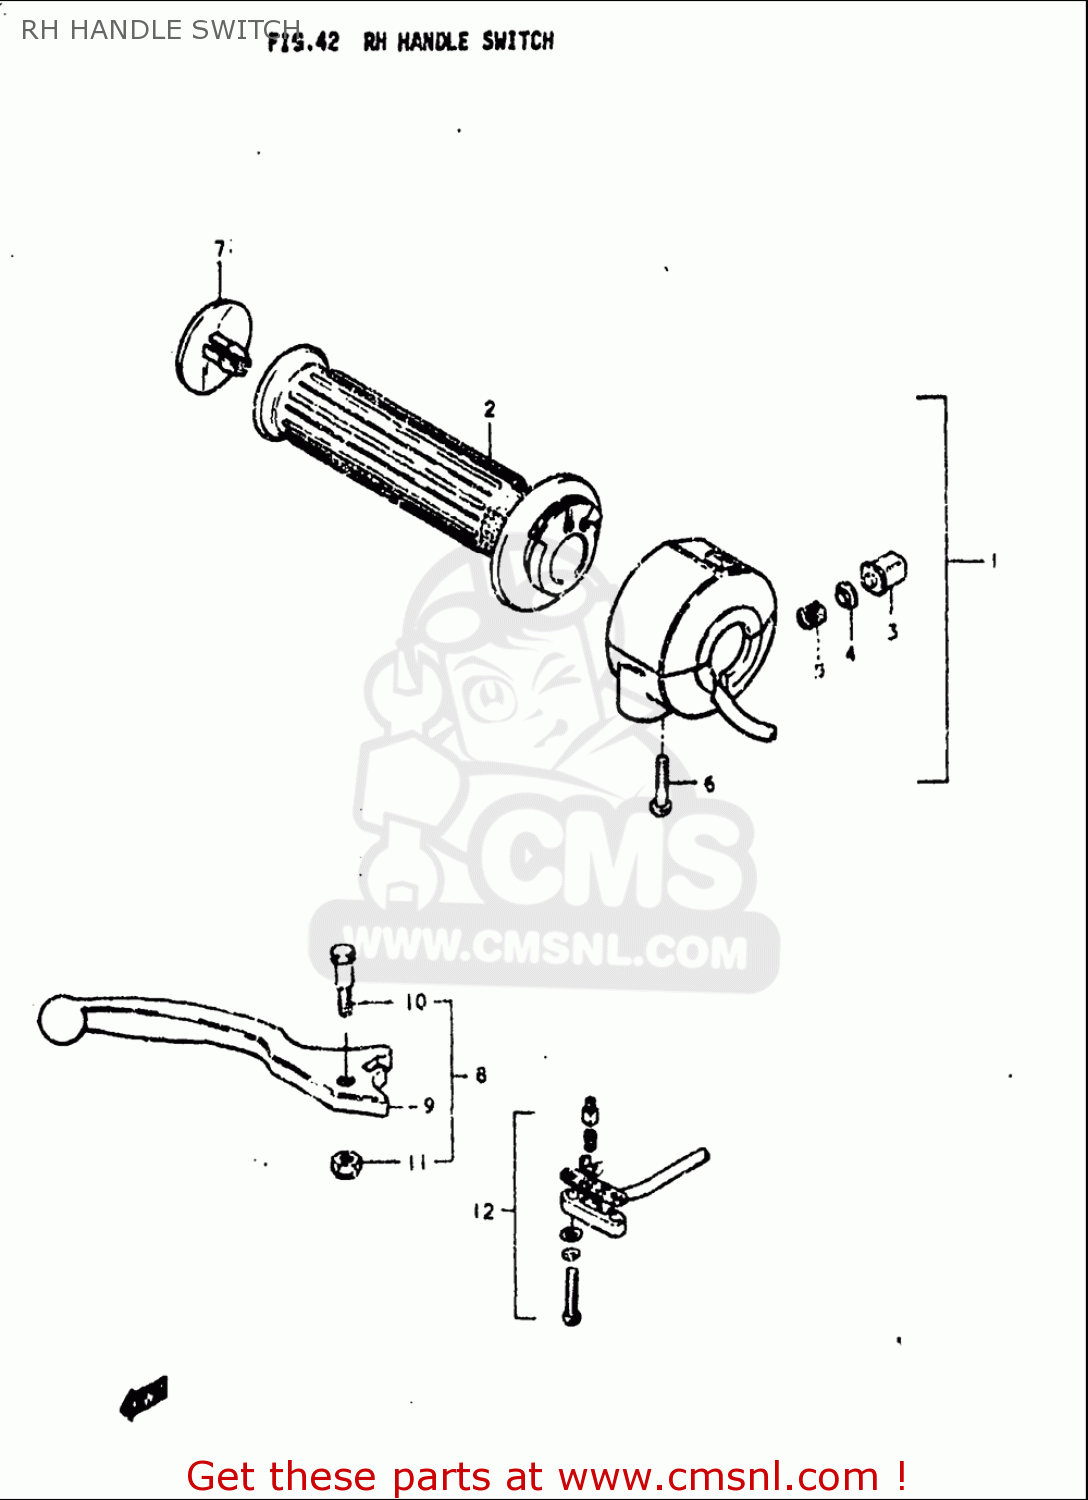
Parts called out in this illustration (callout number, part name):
1	CASE ASSY,THROTTLE
2	GRIP,THROTTLE
3	BUTTON,HORN
4	CONTACT
5	SPRING
6	SCREW
7	CAP,GRIP END
8	LEVER,BRAKE
9	LEVER,BRAKE
10	BOLT
11	NUT 6MM
12	SWITCH ASSY,STOP
